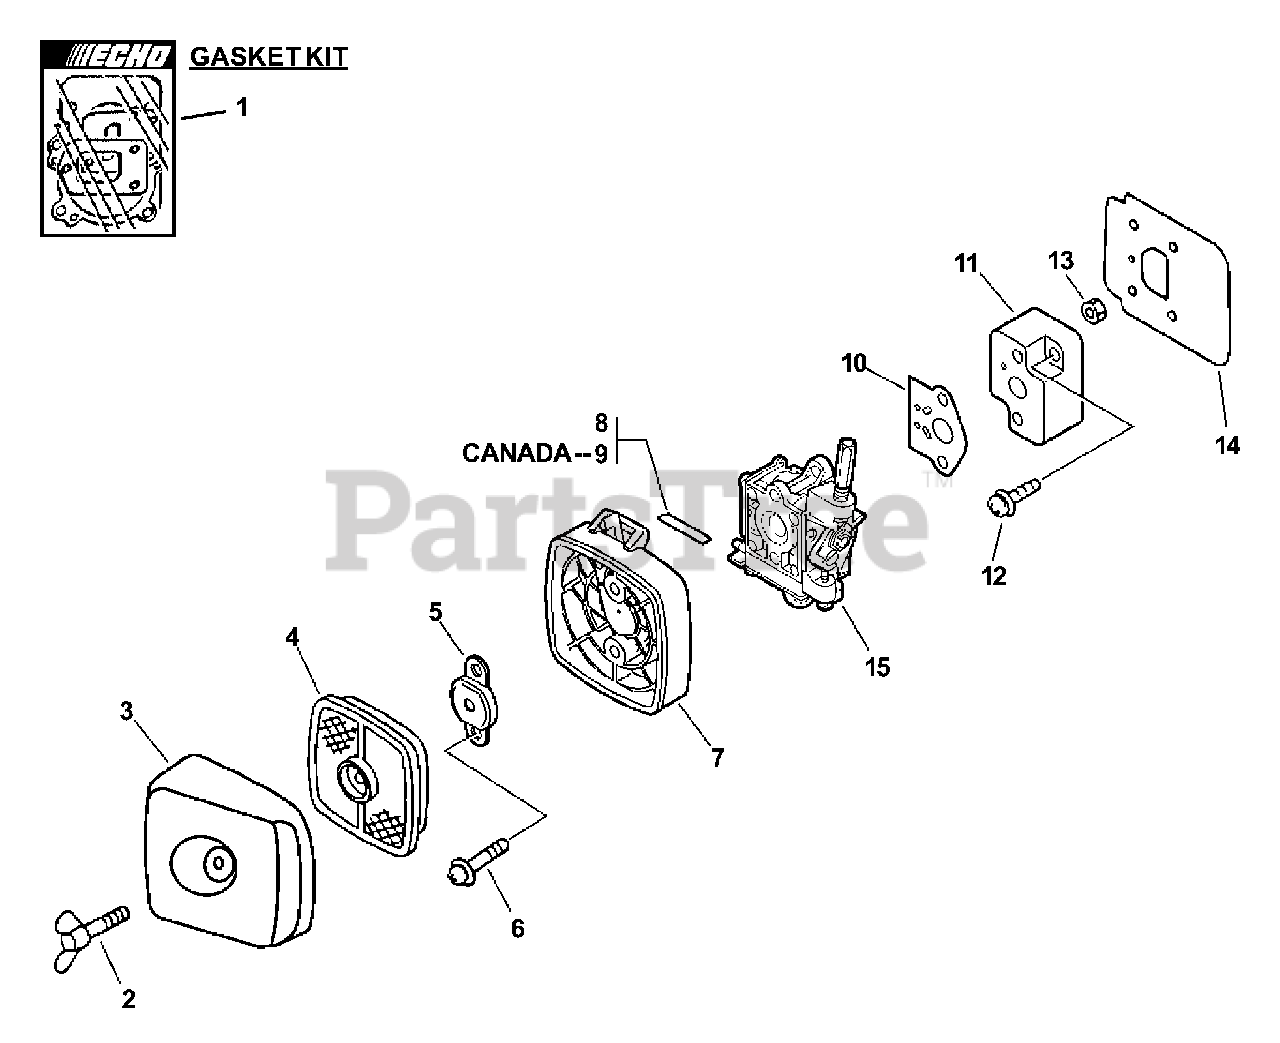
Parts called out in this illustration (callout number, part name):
1	GASKET KIT
2	THUMBSCREW
3	COVER, AIR FILTER - GRAY
4	FILTER, AIR - SINGLE LAYER
5	PLATE, PREVENT
6	SCREW - 5X65
7	CASE, AIR FILTER - GRAY
8	LABEL - CHOKE
9	LABEL - CHOKE
10	GASKET, INTAKE
11	INSULATOR, INTAKE
12	SCREW - 5X20
14	SHIELD, INTAKE
15	CARBURETOR
